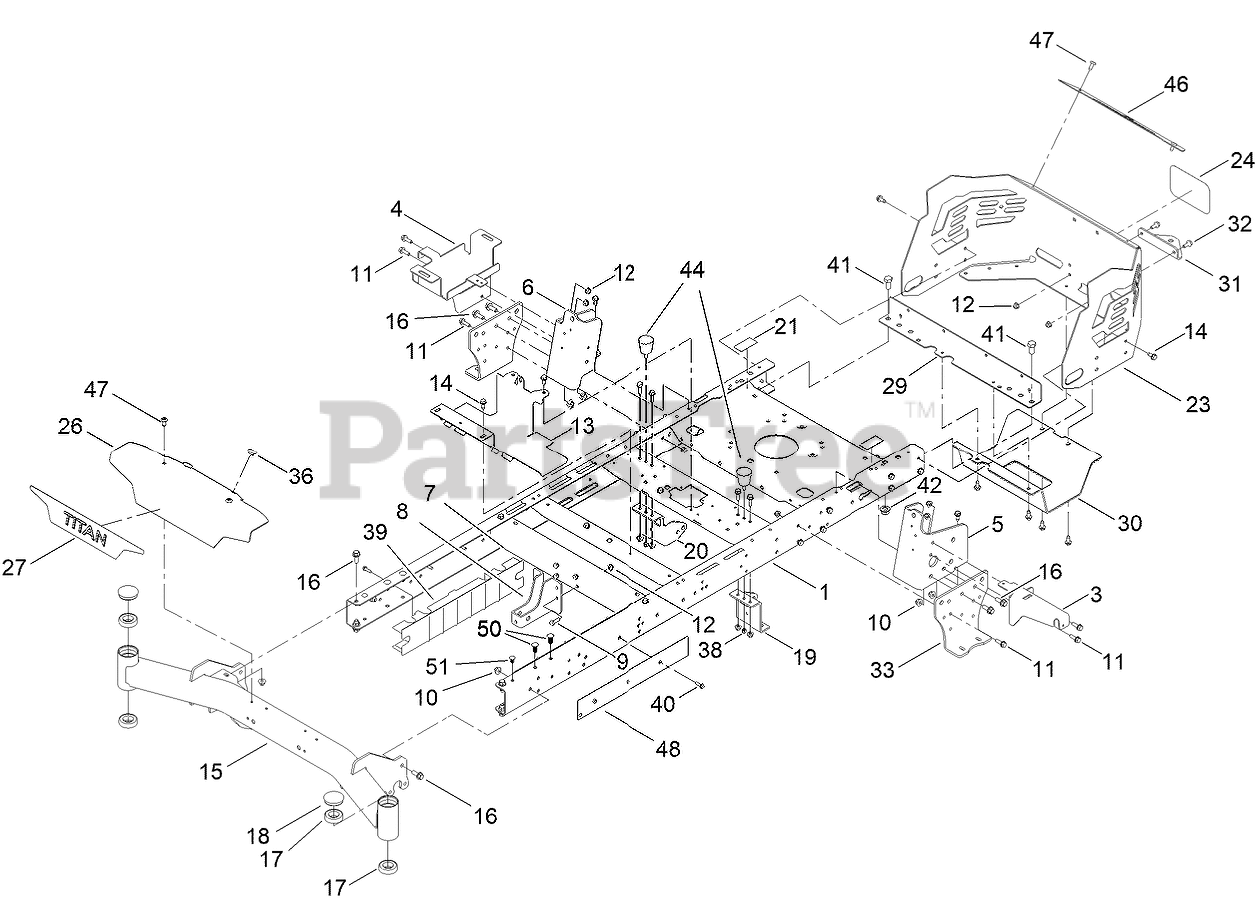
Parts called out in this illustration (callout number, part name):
1	FRAME ASM
3	BRACKET-SUPPORT, POD (LH)
4	TRAY-BATTERY
5	BRACKET-MOUNTING, LH
6	BRACKET-MOUNTING, RH
7	BRACE-CROSS, LOWER
8	BRACKET-MOUNT DAMPER, LOWER
9	SCREW-HH
10	NUT-HF, NI
11	SCREW-HHF
12	NUT-HF, NI
13	BRACKET-MOUNT
14	SCREW-HWHTF
15	FRONT AXLE ASM
16	SCREW-HHF
17	BEARING-BALL
18	CAP-GREASE
19	MOUNT-HYDRO, FRONT (LEFT)
20	MOUNT-HYDRO, FRONT (RIGHT)
21	DECAL-BYPASS
23	GUARD-ENGINE
24	DECAL
26	PLATE-FRONT
27	DECAL-TITAN
29	CROSSMEMBER-REAR, WIDE
30	GUARD-MUFFLER
31	BRACKET-HITCH
32	SCREW-HHF
33	MOUNT-HYDRO
36	BUMPER-SEAT
38	NUT-LOCK, NI
39	GUARD-RAIL
40	SCREW-HWH
41	SCREW-HH
42	NUT-LOCK
44	BUMPER-RUBBER
46	TRIM-GUARD, ENGINE
48	PLATE-FRAME
50	RIVET-PUSH
51	RIVET-PUSH
